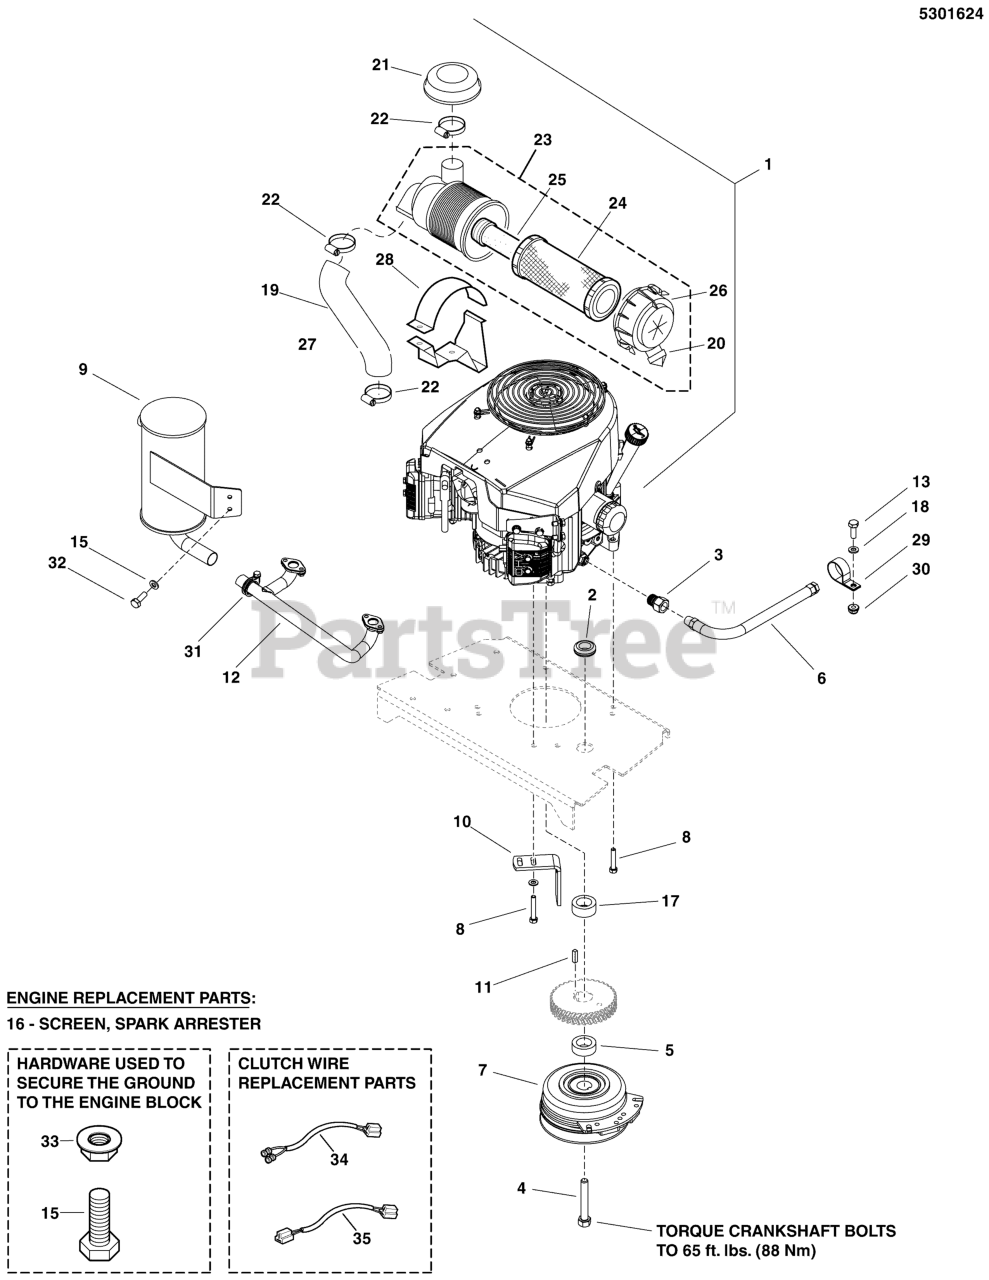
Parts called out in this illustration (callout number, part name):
1	ENGINE, 27HP, KAWASAKI
2	GROMMET, 7/8"
3	ADAPTER, Oil Drain
4	BOLT, CRANKSHAFT,7/16-20X2-1/2, GD8
5	SPACER, 1.13 x 1.75 x .62
6	HOSE, OIL DRAIN
7	CLUTCH WARNER 200 FT-LB 1.13 X 6.323
8	BOLT, HEX FLG, SER, GD5 3/8-16 X 1-1/4" PACH CZ
9	MUFFLER, 27HP KAWASAKI, EVOLUTION
9	KIT, MUFFLER & DECK GUARD, EVO
10	ANCHOR, CLUTCH - BLK
11	KEY, 1/4 SQ X 1
12	MANIFOLD, EXHAUST
13	BOLT, 1/4"-20 X 3/4" GD5 YZ
14	WASHER, 3/8 SAE
15	BOLT, M8-1.25 X 20 MM GD 8.8
16	SCREEN, SPARK ARRESTER (SV)
17	SPACER, 1.13 X 1.75 X .75
18	WASHER, 1/4 SAE
19	AIR INLET TUBE, 22,24&26HP KAWASAKI (SV)
19	AIR INLET TUBE (SV)
20	RUBBER, Dust Valve, 22,24&26HP KAWASAKI (SV)
20	RUBBER, Dust Valve (SV)
21	RAIN CAP, AIR FILTER, 22,24&26HP, KAWASAKI (SV)
21	RAIN CAP, KAWA, DFI
22	CLAMP, HOSE
22	CLAMP, CAP
23	AIR FILTER ASSEMBLY, 22,24&26HP KAWASAKI (SV)
23	AIR FILTER ASSEMBLY (SV)
24	AIR FILTER, PRIMARY,22,24&26HP, KAWASAKI (SV)
24	AIR FILTER, ELEMENT, PRIMARY
25	AIR FILTER, SECONDARY, 22, 24&26HP KAWASAKI (SV)
25	AIR FILTER, ELEMENT, SECONDARY
26	CAP END, FILTER CASE (SV)
26	CAP END, FILTER CASE, 22,24&26HP, KAWASAKI (SV)
27	BRACKET PLATE, LOWER, 22,24&26HP KAWASAKI (SV)
27	BRACKET PLATE, LOWER (SV)
28	BRACKET PLATE, UPPER, 22,24&26HP KAWASAKI (SV)
28	BRACKET PLATE, UPPER 27, 34 & 37 (SV)
29	CLAMP, VINYL INSULATED, 1.00
30	NUT, 1/4-20 Hex Nylock Flange
31	CLAMP, EXHAUST EXTENSION
32	WASHER, 5/16" SAE
33	NUT, M8-1.25 Hex Serrated Flange
34	KIT, CLUTCH WIRE REPAIR
35	WIRE HARNESS, JUMPER, WARNER CLUTCH (SV)
